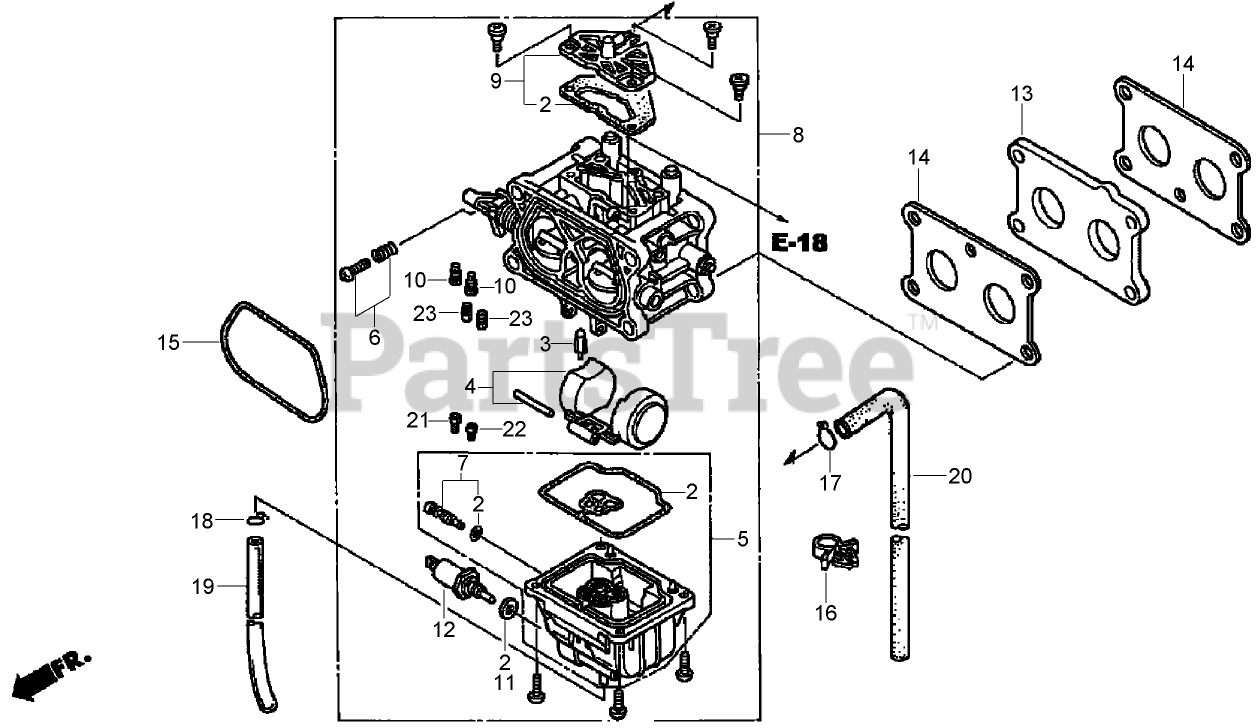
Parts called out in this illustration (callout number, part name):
2	GASKET SET
3	VALVE-FLOAT
4	FLOAT SET
5	FLOAT CHAMBER SET
6	SCREW-SET
7	SCREW-SET, DRAIN
8	CARBURETOR ASM (Up to Engine Serial No. 1014986)
8	CARBURETOR ASM (BW02B C) (Up to Engine Serial No. 1027210)
8	CARBURETOR ASM (BW02B C) (From Engine Serial No.1027211 to 1061017)
8	CARBURETOR ASM (BW02C A) (From Engine Serial No. 1061018)
9	AIR VENT COVER SET
10	CAP
11	GASKET
12	SOLENOID VALVE ASM
13	INSULATOR-CARBURETOR
14	GASKET-INSULATOR
15	GASKET-CLEANER, AIR
16	CLIP-HARNESS, WIRE
17	CLIP-TUBE (B8)
18	CLIP-TUBE (B6.5)
19	HOSE-BULK, VINYL (4X7X8000) (4X7X300)
20	HOSE-BULK, VACUUM (45X1000) (45X400)
21	JET-MAIN (No. 82.5)
21	JET-MAIN (No. 85)
21	JET-MAIN (No. 87.5)
22	JET-MAIN (No. 85)
22	JET-MAIN (No. 87.5)
22	JET-MAIN (No. 90)
23	JET-PILOT (No. 37.5)
